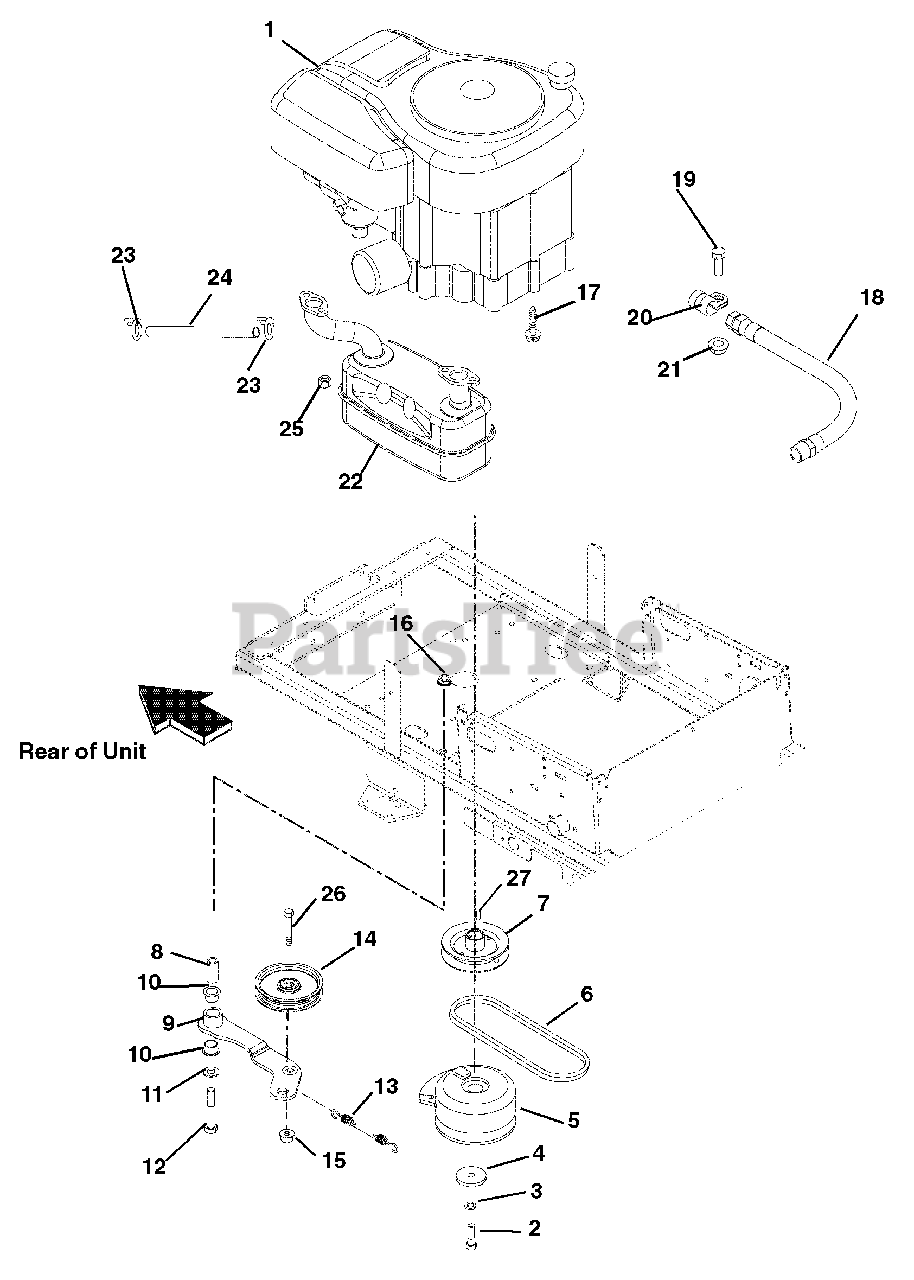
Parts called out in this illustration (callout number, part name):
1	ENGINE, 20 HP SINGLE KOHLER
2	7/16-20X3 HHCS GR8 YWZC
3	@WSHR-LK .44X.109 REG YWZC
4	WSHR-FL-STL .469X2.00X.25 YWZC
5	CLUTCH, ELECTRIC
6	V-BELT, HA-WRAPPED
7	PLY-V 3.75X1.0 A SECTION W/KEY
8	BSHG-SLV .500X.750X1.560
9	WMT, IDLER
10	BSHG-FLG 0.75X0.875X.625X1.125
11	@WSHR-FL-STL.531X1.06X.095YWZC
12	@BLT-HEX .50-13X3.25 GR5 YWZC
13	SPRING, EXT
14	IDLER-FLAT 4.00 X .38 NWHAMSHR
15	@NUT-LK-NYL-FLG .38-16 YWZC
16	@NUT-LK-TOP-FLG .50-13 YWZC
17	@BLT-HEX .31-18X1.75 GR5 YWZC
18	HOSE, HYD .38-11-0K M6N0-F6J0
19	@BLT-HEX .31-18X.75 GR5 YWZC
20	CLAMP, CUSHIONED STEEL .75
21	@NUT-LK-NYL-FLG .31-18 YWZC
22	MUFFLER, TWIN KOHLER (EES)
23	CLAMP-HOSE WIRE .490/.510X.116
24	GAS LINE-BULK 1/4" I.D.
25	NUT, TOP LOCK FLG 8X1.25 YWZC
26	@BLT-HEX .38-16X2.00 GR5 YWZC
27	KEY-SQ .25X1.0X.25 SAE 8630
